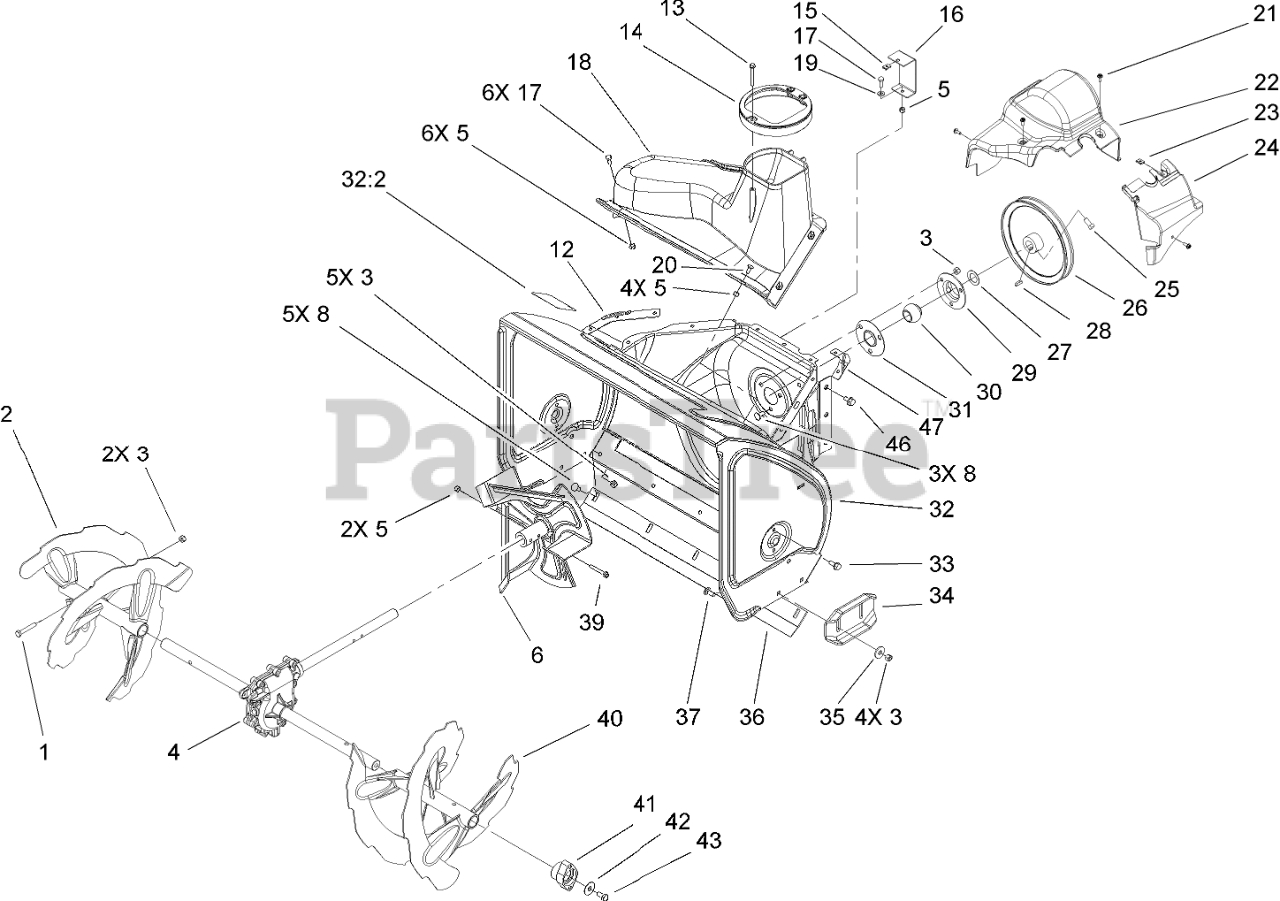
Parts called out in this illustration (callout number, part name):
1	SCREW-HH
2	RH AUGER ASM
3	NUT-LOCK, NI
4	AUGER GEARCASE ASM
5	NUT-LOCK, NI
6	IMPELLER ASM
8	SCREW-CARR
12	SEAL-FLANGE, COVER
13	SCREW-PLASTITE
14	GUIDE-CHUTE
15	NUT-SPEED, U-TYPE
16	BRACKET-COVER, CLIP NUT
17	SCREW-HH
19	WASHER-FLAT
20	BOLT-CARR
21	SCREW-HWH
22	COVER-BELT
23	NUT-SPEED
24	COVER-EXTENSION, BELT
25	SCREW-SET, SQH
26	PULLEY-IMPELLER
27	WASHER-THRUST
28	KEY-WOODRUFF
29	FLANGE-CUP, BEARING
30	BEARING-BALL
31	FLANGE-CUP, BEARING
32	HOUSING-AUGER, 28 INCH
32:2	DECAL-DANGER, AUGER
33	SCREW-HWHTF
35	WASHER
36	SCRAPER-FIXED
37	SCREW-CARR
39	SCREW-HHF
40	LH AUGER ASM
41	BEARING-AUGER
42	WASHER
43	SCREW-HH
46	SCREW-HWHTF
